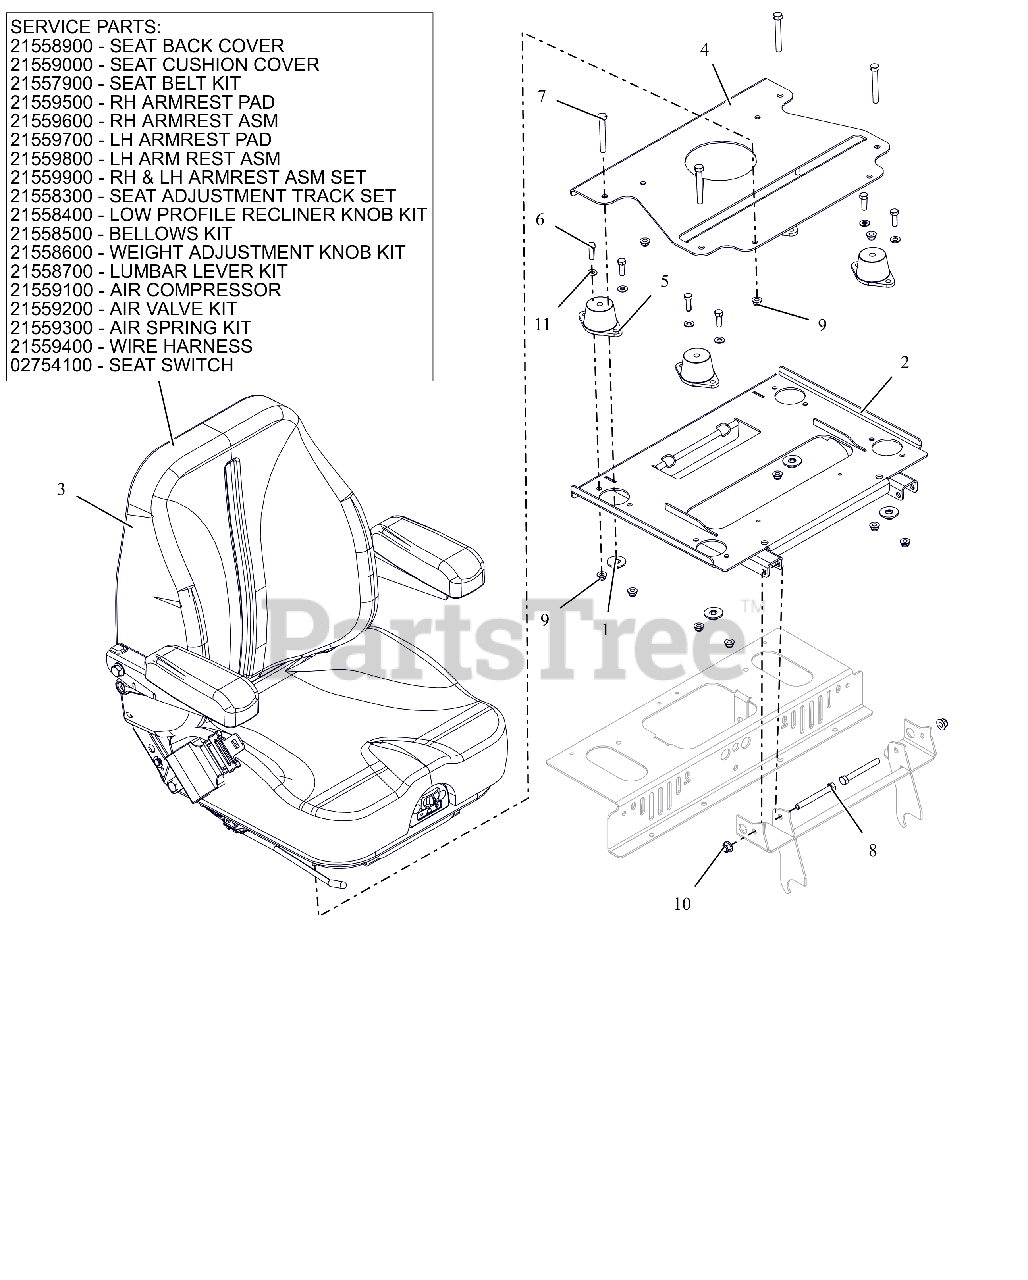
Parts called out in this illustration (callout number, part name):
1	WLDMT, SEAT RETAINER
2	SEAT ISO MTG WMT W/SFTY DECAL
3	SEAT, AIR SUSPENSION
3	COVER, SEAT BACK
3	COVER, SEAT CUSHION
3	KIT, SEAT BELT
3	PAD, RH ARMREST
3	ASM, RH ARMREST
3	PAD, LH ARMREST
3	ASM LH ARMREST
3	SET, RH & LH ARMREST ASM
3	SET, SEAT ADJUSTMENT TRACK
3	KIT, LOW PROFILE RECLINER KNOB
3	KIT, BELLOWS
3	KIT, WEIGHT ADJUSTMENT KNOB
3	KIT, LUMBAR LEVER
3	COMPRESSOR, AIR RIDE SEAT
3	KIT, AIR VALVE AND LINE
3	KIT, AIR SPRING
3	HARNESS, SEAT WIRE
3	SWITCH- SNAP MTG N.O.
4	SEAT MOUNTING PLATE - RED
5	MOUNT, ISOLATOR
6	BLT,HEX .31-18X1.00 G5 ZCC
7	BLT, HEX .38-16X2.75 G5 ZCC
8	BLT, HEX .38-16X3.25 G5 ZCC
9	NUT,NYL-FLG .31-18 GF ZCC
10	NUT,NYL-FLG .38-16 GF ZCC
11	WSHR,FLT .344X.688X.065 ZCC
